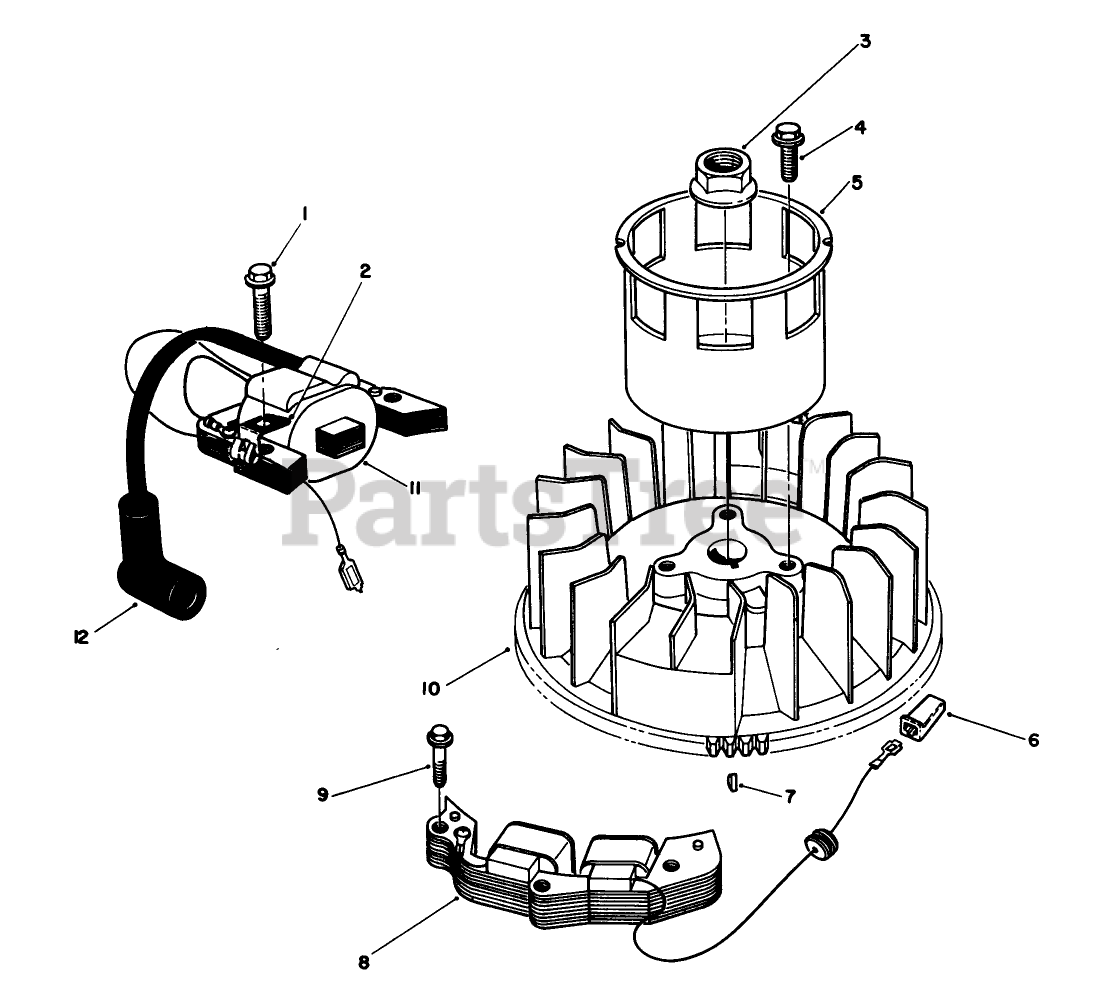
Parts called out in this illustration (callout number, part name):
2	CLAMP
6	CONNECTOR BODY
10	FLYWHEEL
11	COIL ASM
12	COVER
